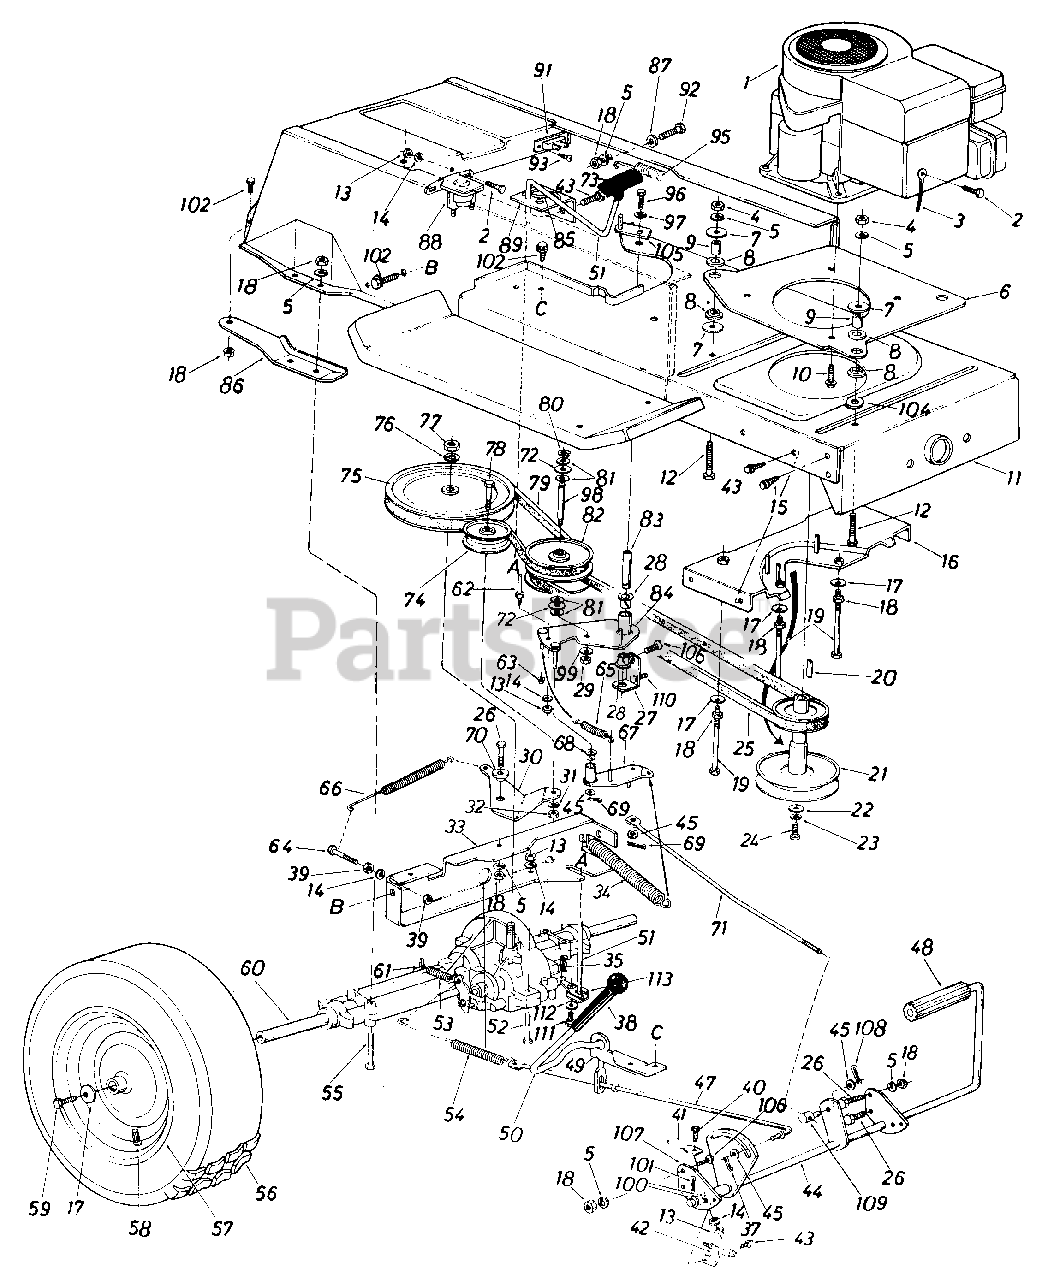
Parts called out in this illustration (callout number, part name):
1	Engine
2	Hex Bolt 1/4-20 X .621' Lg.
3	Electric Ground Wire
4	Hex Nut 5/16-24 Thd.
5	L-Wash. 5/16" I.D.
6	Engine Mounting Plate
7	Fl-Wash. .320" I.D. x 1.25"
8	Engine Mounting Grommet
9	Spacer
10	Hex Bolt 3/8-16 X 1.25" Lg.
11	Lower Frame Ass'y.
12	Hex Bolt 5/16-24 X 1.25"
13	Hex Nut 1/4-20 Thd.
14	L-Wash. 1/4" I.D.
15	Hex Wash. Hd. AB-Tap Scr. 5/16" x.75" Lg.
16	Belt Guard Brkt. Ass'y.
17	Bell-Wash. .345" I.D. x .88"
18	Hex Nut 5/16-18 Thd.
19	Hex Bolt 5/16-18 X 5.25" Lg.
20	Sq. Key 1/4" X 1/4" X 2.00"
21	Engine Pulley
22	Fl-Wash. 7/16" I.D. x 1.25"
23	L-Wash. 7/16" I.D.
24	Hex Bolt 7/16-20 X 1.50" Lg.
25	Variable-Speed Belt .715 X 53" Lg.
27	Bearing Shaft Bracket Ass'y .
28	Flanged Nyliner Brg. 5/8" I.D. x .88" Lg.
29	Hex Nut 3/8-24 Thd.
30	Idler Bracket
31	L-Wash. 3/8" I.D.
32	Hex Nut 3/8-24 Thd.
33	Transaxle Support Brkt.
34	Ext. Spring .94" O.D. x 6.7
35	Inter. Cott-Pin
37	Cotter Pin 3/32" Dia. x .75"
39	Hex Nut 1/4-28 Thd.
40	Hex Bolt 1/4-20 X l.OO Lg.
41	Switch Actuator
42	Safety Switch
43	Hex Wash. Hd. S-Tap Scr 1/4-20 X .50" Lg.
44	Clutch & Brake Pedal Ass'y.
45	Fl-Wash.
47	Brake Rod 20.9" Lg.
48	Foot Pad
49	Brake Lever Bracket
50	Hill Holder Brake Handle
51	Shift Lever Ass'y.
52	Hex Bolt 1/4-28 X 1.75" Lg.
53	Ext. Spring .38" O.D. x 2.5"
54	Ext. Spring .59" O.D. x 7.08"
55	Hex Bolt 5/16-18 X 2.75"*
56	" Wheel Ass'y. Comp.
57	Wheel Rim Only
58	Air Valve
59	Hex Bolt 5/16-24 x .75" Lg.
60	Transaxle Complete
61	Brake Return Spring Anchor
62	Belt Guard Pin 1/4-20 Thd.
63	Cap Speed Nut 1/4" Dia.
64	Hex Bolt 1/4-28 x 1.25" Lg.
65	Ext. Spring .50" Dia.
66	Ext. Spring .62" O.D. x 6.12"
67	Variable Speed Torque Brkt. Ass'y.
68	Flanged Bearing
69	Cotter Pin 3132" Dia.
70	Shoulder Spacer .500" Dia. x.27" Lg.
71	Speed Control Link
72	Truss Bearing .56 Dia. x 1 .25"
73	"T" Knob
74	Fl-ldler Pulley 3.25" x 1.0"
75	1/2" "V"-Pulley 8.0" O.D. x .501 " I.D.
76	L-Wash. 1/2" I.D.
77	Hex Jam Nut 1/2-20 Thd*
78	Hex Bolt 3/8-24 x .75" Lg.
79	Variable Speed Belt .715 x 44" Lg.
80	Snap Ring .56" Dia.
82	Variable Speed Pulley Ass'y. 5" O.D.
83	Bearing Shaft
84	Variable Speed Brkt. Ass'y.
85	Comp. Spring Clip
86	Transaxle Support Brkt. R. H .
87	Fl-Wash. .34 I.D. x 1.12 O.D.
88	Solenoid
89	Shift Lever Bracket
91	Circuit Breaker
92	Hex Bolt 5/16-18 x 1.50" Lg.
93	Truss Hd. Phil. Scr. #10 x 1/2 " Lg.
95	Ext. Spring .99" O.D. x 11.0"
96	Hex Bolt 3/8-24 x .75" Lg.
97	Bell-Wash. .38" I.D. x .88"
98	Shaft .56" Dia. x 3.875" Lg.
99	Bell-Wash. .39" I.D. x 1.12"
100	Fl-Wash.
101	Cotter Pin 3/32" Dia. x 1.0"
102	Hex Wash. Hd. Scr. 5/16-18 x .62" Lg.
104	Fl-Wash. .32" I.D. x 1.25"
105	Belt Guard
106	Truss Mach. Scr. 5/16-18 x .75" Lg.
107	Pedal Bracket
108	Cotter Pin 3/32" Dia. x .75"
109	Ferrule
110	Truss Phillips Hd. Scr. 5/16-18 x 1.0" Lg.
111	Hex Bolt 1/4-28 x .50" Lg.
112	Bell-Wash. .265" I.D. x .75"
113	Shift Lever Link Ass'y.
